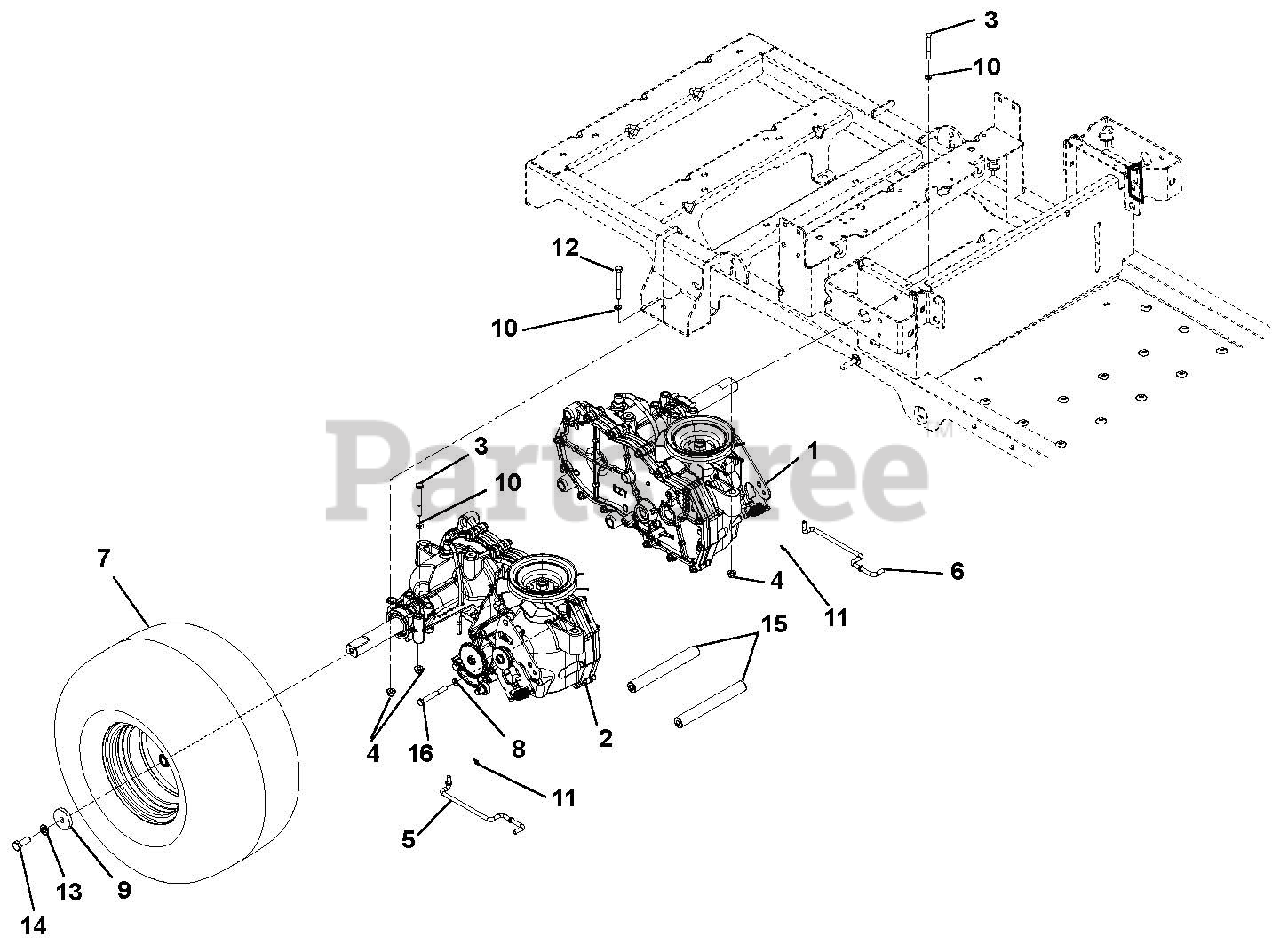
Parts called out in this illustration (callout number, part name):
1	Transaxle, Left Hand EZT D-Shaft (915210)
1	Transaxle, Left Hand EZT D-Shaft Long (915212, 214)
2	Transaxle, Right Hand EZT D-Shaft (915210)
2	Transaxle, Right Hand EZT D-Shaft Long (915212, 214)
3	Bolt, Hex .31-18 x 2.25
4	Nut 5/16-18 Flange Nyloc
5	Dump Valve, Right Hand
6	Dump Valve, Left Hand
7	Tire Assembly 18 x 6.5-8 2 Ply DSHAFT (915210)
7	Tire/Wheel Assembly, 18 x 8.5-8 Center (915212)
7	Tire/Wheel Assembly, 18 x 9.50-8 Offset (915214)
8	Washer, Flat Steel .406 x 1.00 x .188
9	Washer, Flat Steel .406 x 1.50 x .245
10	Washer, Flat Steel .38 x .875 x .083
11	Pin, Hair, Internal .06 x .18 x .77
12	Bolt, Hex .31-18 x 2.75
13	Washer, Locking .38 x .094 Regular
14	Bolt, Hex .38-16 x 1.00 YWZC EP30
15	Shaft, Transaxle Brace
16	BOLT, HEX .38-116 X 2.50
